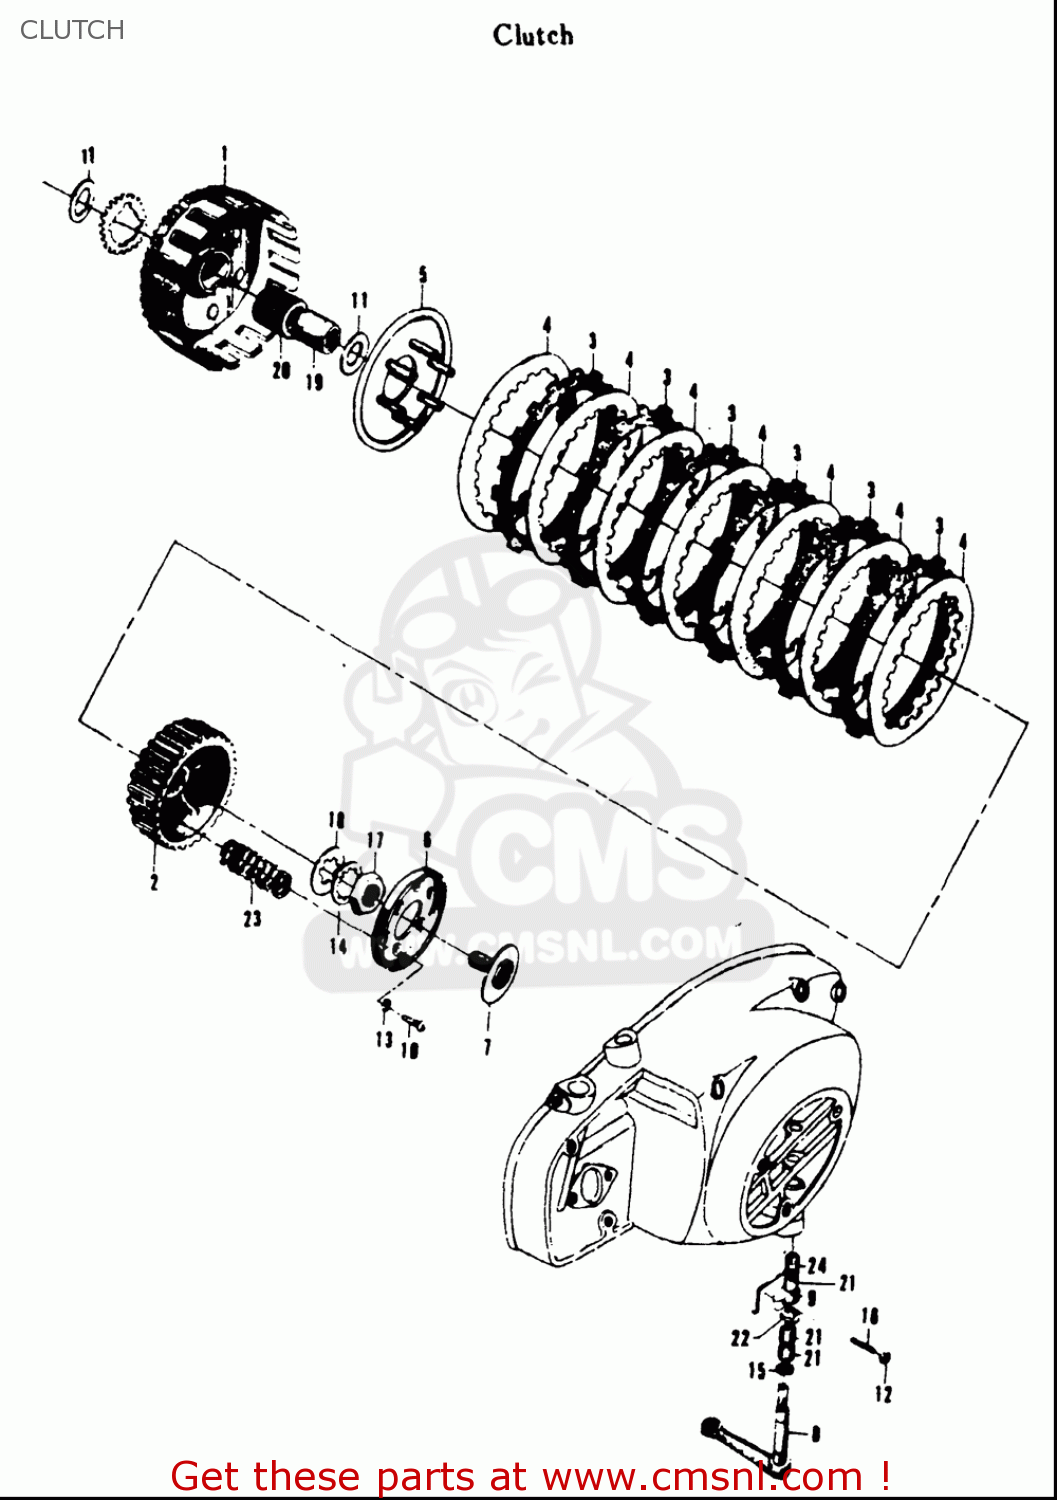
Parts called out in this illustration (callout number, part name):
10	SCREW
11	WASHER(20X38X2)
12	NUT
13	WASHER,LOCK
15	SEAL,OIL(10X17X5)
17	NUT
18	WASHER,LOCK
21	BUSHING
22	E RING
